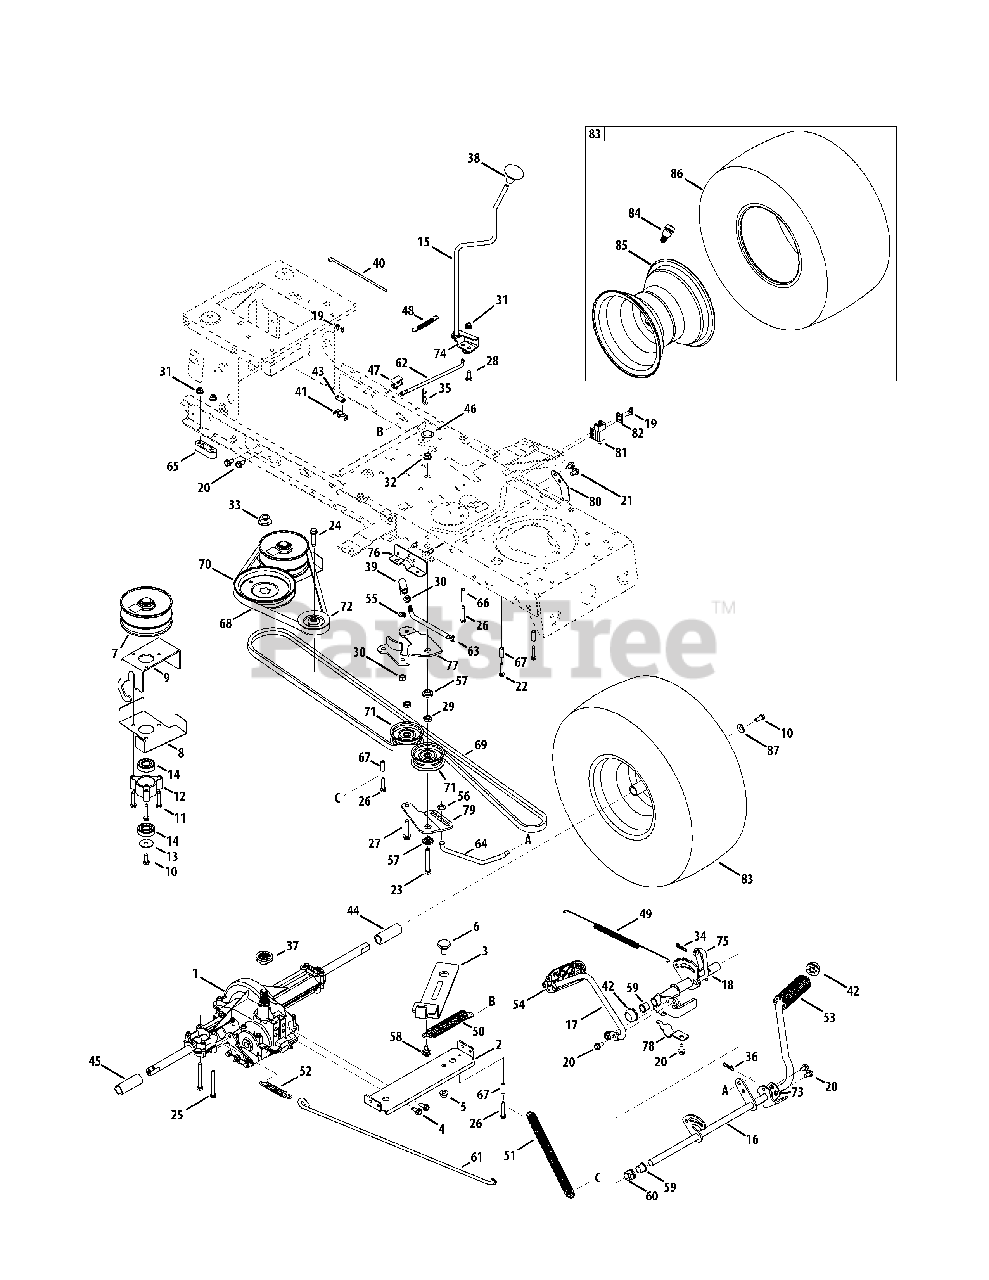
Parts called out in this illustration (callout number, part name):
1	Assembly, Autodrive
2	Auto-drive Bracket Assembly
3	Idler Bracket Assembly
4	Tap Screw, 5/16-18 x 0.750
5	Flange Lock Nut, 3/8-16
6	Shoulder Screw, .625 x .217
7	Pulley Assembly, Var. Spd. 4.75 Od
8	Belt Keeper Assembly
9	Variable Bracket Assembly
10	Hex Screw 5/16-24 .750
11	Tap Screw, 1/4-20 1.500
12	Bearing Cup
13	Wash, Flat .330 X 1.25 X .06
14	Ball Bearing, 17 x 40 x 12.6203
15	Lvr Assembly, Shft
16	Pedal Assembly, Drive, Autodrive
17	Pedal Assembly, Cont, Autodrive
18	Bracket Assembly, Pedal, Autodrive
19	Screw, Ab, #8-18, 0.500
20	Screw, Tt, 5/16-18, .750
21	Screw, Tt, 5/16-18, 0.625
22	Screw, Tt, 1/4-20, 1.250
23	Hex Hd. Screw, 3/8-16, 2.50
24	Screw, Ttsems, 3/8-16, 1.500
25	Hex Hd. Screw, 5/16-18, 3.50
26	Screw, Tt, 1/4-20, 1.625,
27	Screw, Tt, 3/8-16 x 1.75
28	Hex Hd. Screw, 5/16-18, .75
29	Nut, Jam, 7/16-20
30	Nut, Hex, 3/8-24
31	Nut, Flange Lock Nut, 5/16-18
32	Nut, Flange Lock Nut, 3/8-16
33	Nut, Flg, 9/16-18
34	Pin, Cot, 3/32, 1.0
35	Pin, Cotter Int- .125 Dia
36	Pin, Cot, Bow-Tie 72
37	Hub, Pulley, 5/8 Spline
38	Knob, Shft
39	Ball, Joint
40	Cable, Tie, 3/16 X .05 X 7.4
41	Switch, Spring, Short
42	Cap, Push 5/8
43	Plate, Insulator Nut
44	Sleeve, .758 X .821 X 3.3125
45	Sleeve, .758 X .821 X 2.4375
46	Plug, Deck Hole, 7/8
47	Shift Plate Bearing
48	Spring, Ext, .38 Od X 3.25 Lg
49	Spring, Extn, .70 Dia X 12.00 Lg
50	Spring, Extn, .97 Od X 6.18 Lg
51	Spring, Extn, .56 X 12.05 x .068
52	Spring, Extn, .59 Od X 4.00 Lg
53	Pad, Foot, 4.0 Long
54	Pad, Cont
55	Wash, Lock, 3/8, Regular Duty
56	Wash, Flat, .375 X .738 X .063
57	Spacer, Shoulder, 1.00 X .38 X .38
58	Screw, Shoulder, .43x.29, Tt, 5/16-18
59	Bearing, Flg, .630 Idx .695 Od X .60
60	Bearing, Hex Flg, .628 Id, Split
61	Rod, Brake, Trans
62	Rod, Shift, Stretch 46"
63	Rod, Adj, Idlr, 3/8
64	Rod, Trans, Footpedal Bypass
65	Spacer, T-Axle .68
66	Spacer, .260 X .372 X 1.420 Lg
67	Spacer, .260 X .375 X 1.030 Lg
68	Belt, V Typ, 5l X 40.9 Lg Poly
69	Belt, V Typ, 5l, 90.80, Poly
70	Pulley, Idlr, Flat 7.25 Od
71	Pulley, Idlr, Flat 2.75 Od
72	Pulley, Idlr, V-Type X 3.06
73	Bracket, Ped, Support Lt-5
74	Bracket, Shft, Adj
75	Plt, Bracket, Reinforcement
76	Bracket, Ped, Frame Rh
77	Bracket, Idlr, Dbl Autodrive
78	Bracket, Supt, Pedal Stap
79	Bracket, Idlr, Center Dbl
81	Interlock Switch
82	Switch Plate
83	Wheel Assembly, 18 x 9.5 x 8 Sq. Sh.
84	Rim Assembly
85	Valve Stem
87	Bell Washer, .340 x .872 x .060
